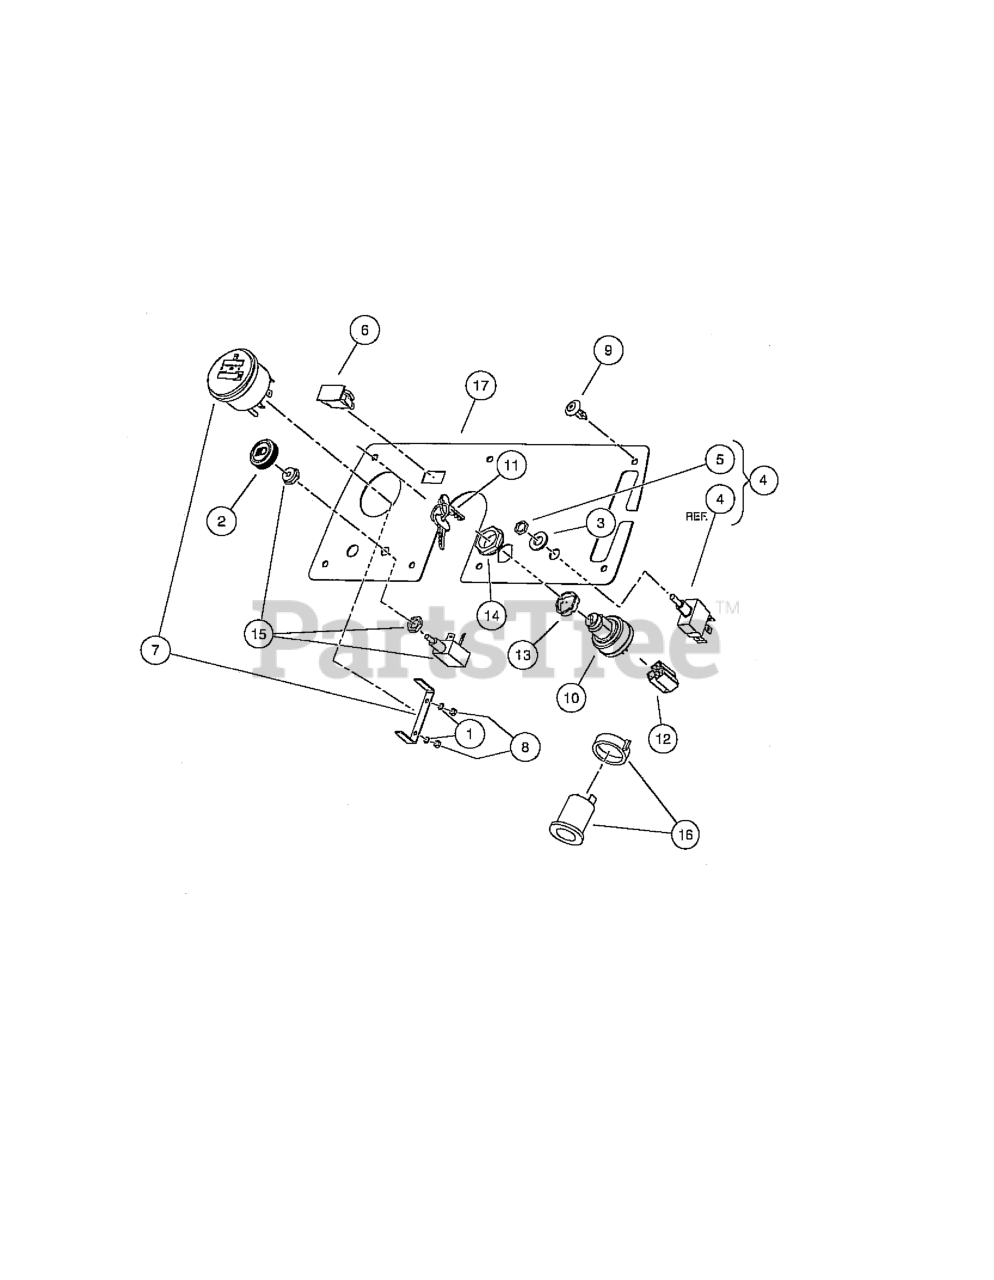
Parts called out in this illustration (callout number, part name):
1	Lockwasher, M4
2	LIGHT SWITCH KNOB
3	WASHER, 7/16 FLAT
4	TOGGLE SWITCH
6	LIGHT, OIL
7	GAUGE FUEL/HOUR
8	NUT, M4-.7
9	SCREW, TUFLOK PANEL, 1/4
10	KEY SWITCH 12V KEY START
13	SPACER, KEYSWITCH
14	NUT, KEYSWITCH
15	SWITCH, LIGHT
16	ACCESSORY RECEPTACLE
17	PANEL, INSTRUMENT, GAS
